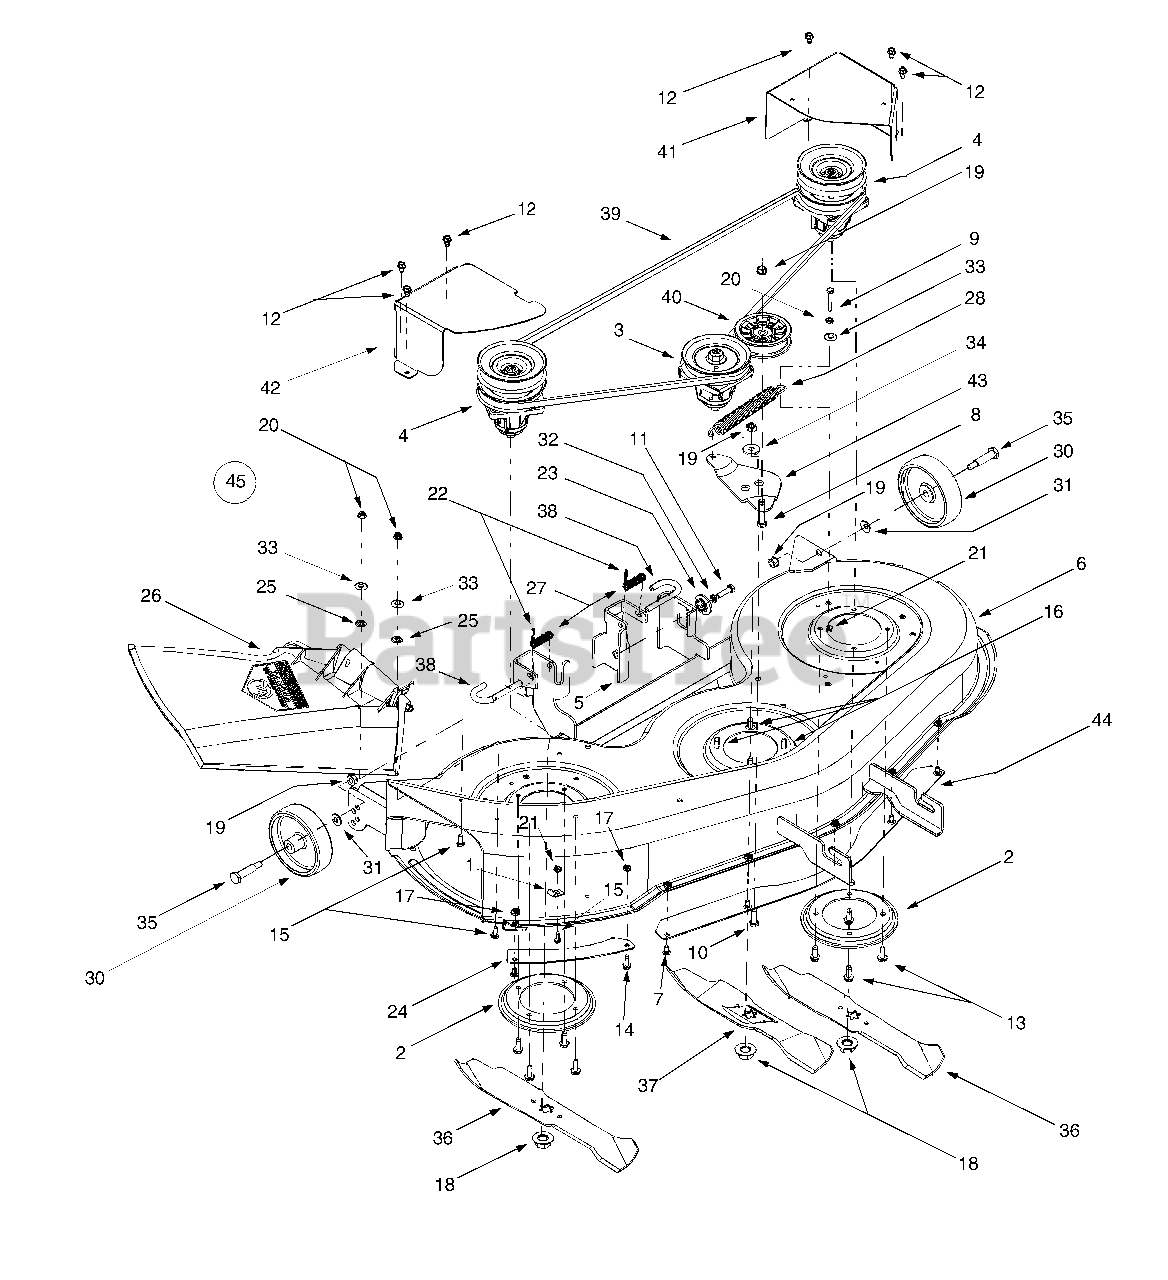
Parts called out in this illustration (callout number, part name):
1	Retainer Hook
4	Double Pulley Spindle Assembly
8	Hex Cap Screw, 3/8-16 x 1.75
9	Hex Cap Screw, 1/4-20 x 2.0
10	Hex Cap Screw, 3/8-16 x 1.0
11	Hex Cap Screw, 5/16-18 x 1.25
12	Self-tapping Screw,1/4-20 x .5
13	Self-tapping Screw,15/16-18 x .875
14	Hex Screw, 1/4-20 x .75
15	Hex Cap Screw, 1/4-20 x .62
16	Self-tapping Screw, 5/16-18 x .75
17	Hex Sems Nut, 1/4-20
18	Hex Flange Nut, 5/8-18
19	Flange Lock Nut, 3/8-16
20	Hex Nut, 1/4-20
21	Hex Flange Lock Nut, 1/4-20
22	Cotter Pin, 1/8 x 1.25
23	Deck Adjustment Gear
25	Push Nut. .25 x .5
26	Side Discharge Chute Assembly
27	Compression Spring, .406 x .531 x 1.75
28	Extension Spring, .91 x 7.33
30	Deck Wheel, 5 x 1.38
31	Bell Washer, .401 x .87 x .063
32	Lock Washer, 5/16
33	Bell Washer, .265 x .75 x .062
34	Shoulder Spacer, .625 x 1.16
35	Shoulder Screw, .498 x 1.53
36	Three-in-one Blade, Star Center, 16.28"
37	Three-in-one Blade, Star Center, 14.88"
38	Deck Release Pin
39	Deck Belt
40	Flat Idler Pulley, 3.5 OD
